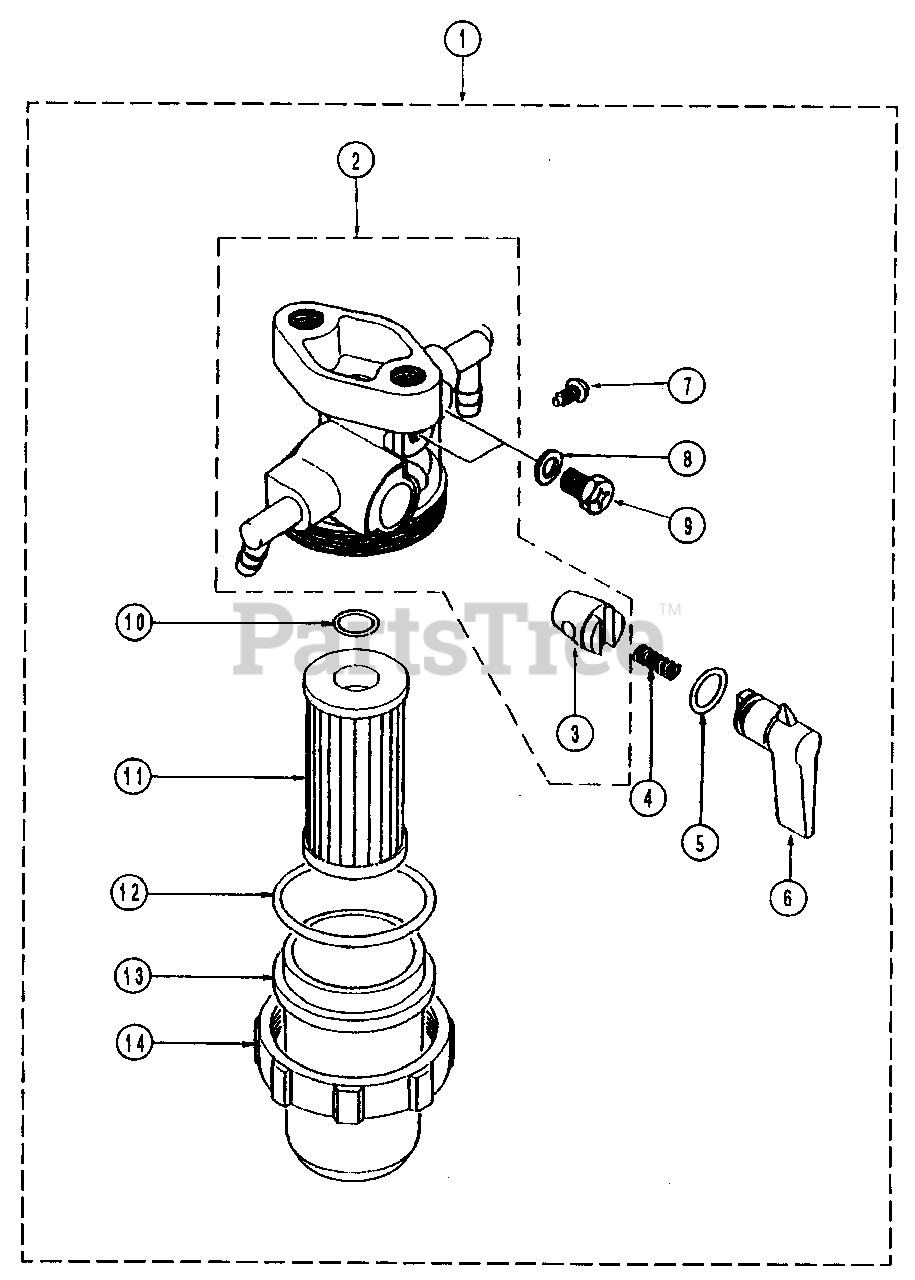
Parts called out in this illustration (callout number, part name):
1	Filter Ass'y.
2	Body Sub Ass'y,
3	Valve
4	Spring, Valve
5	O-Ring, Valve
9	Screw, Air Vent
10	O-Ring, Element
11	Element
12	O-Ring, Filter Cup
13	Cup, Filter
